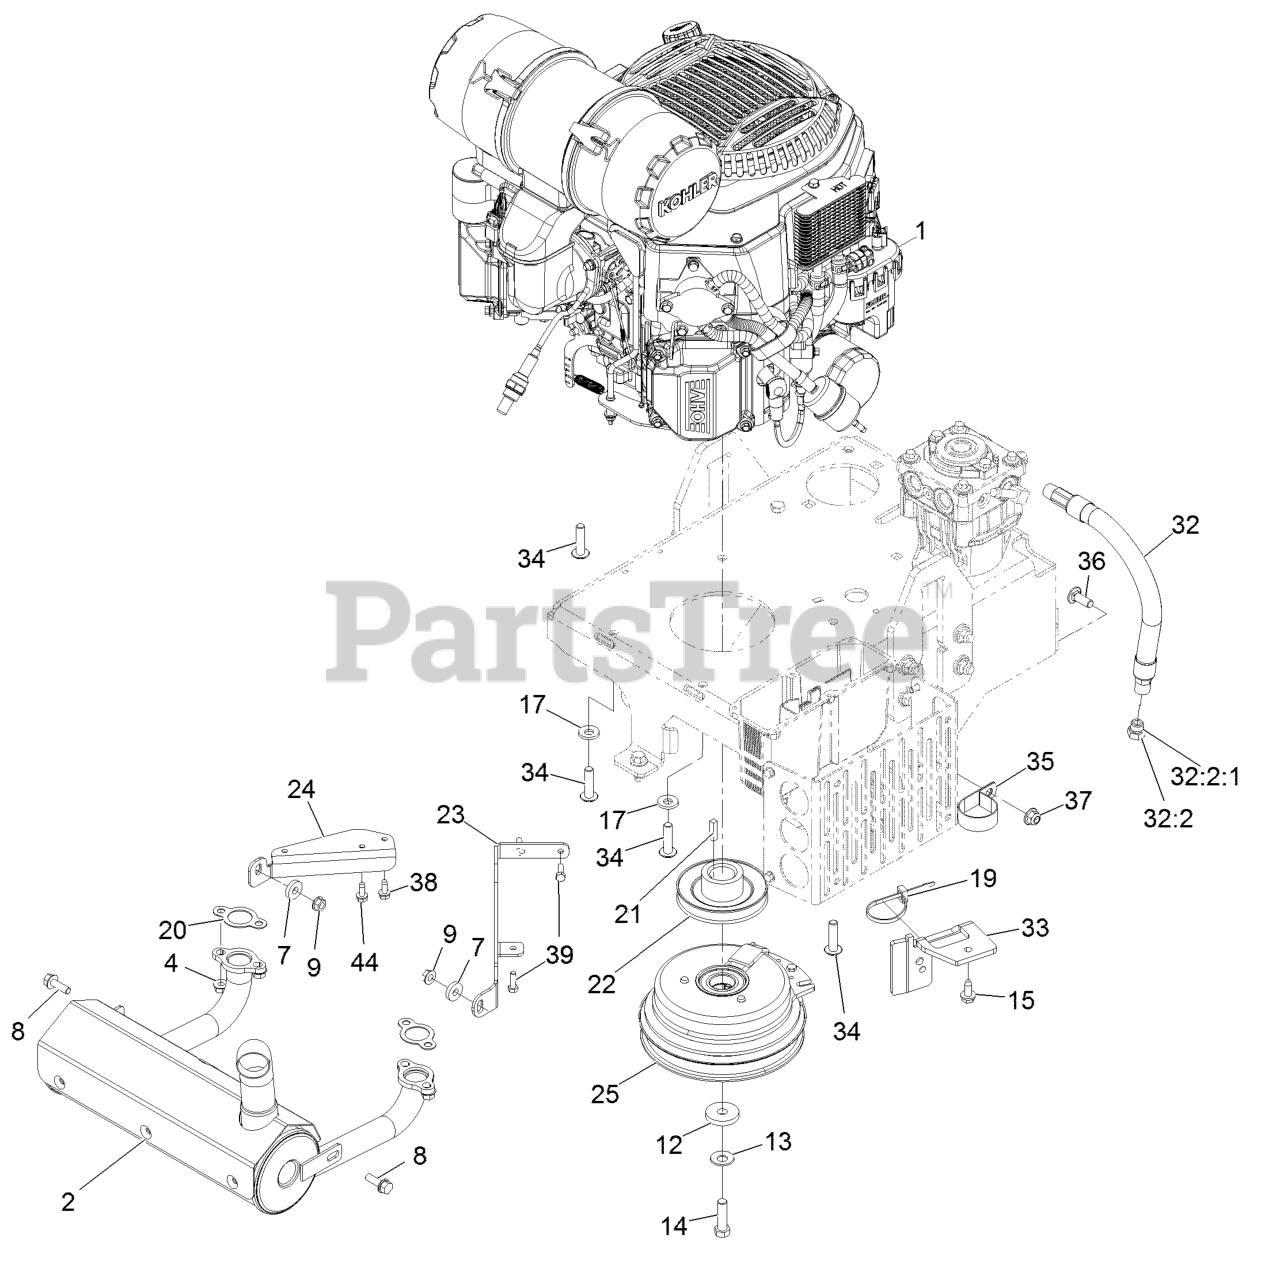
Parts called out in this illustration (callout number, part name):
4	NUT-FLANGE
8	SCREW-HHF
12	WASHER
13	WASHER-SPRING
14	SCREW-HH
15	Screw-HWH 5/16-18 X 3/4 Tf
17	WASHER-BELLEVILLE
19	TIE-CABLE
20	GASKET-EXHAUST
23	MOUNT, MUFFLER-LT
24	MOUNT, MUFFLER-RT
25	CLUTCH-200 FT-LB, 1.125 B
32	OIL DRAIN HOSE ASM
32:2	PLUG-HH
32:2:1	O-RING
33	BRACKET-ANCHOR, CLUTCH
34	SCREW-BHTF
35	CLAMP-R
36	SCREW-CARR
37	NUT-HF, NI
38	SCREW-HWHTF
39	SCREW-HH M6-1 X 20Mm W/Patch
44	SCREW-HWHTF
